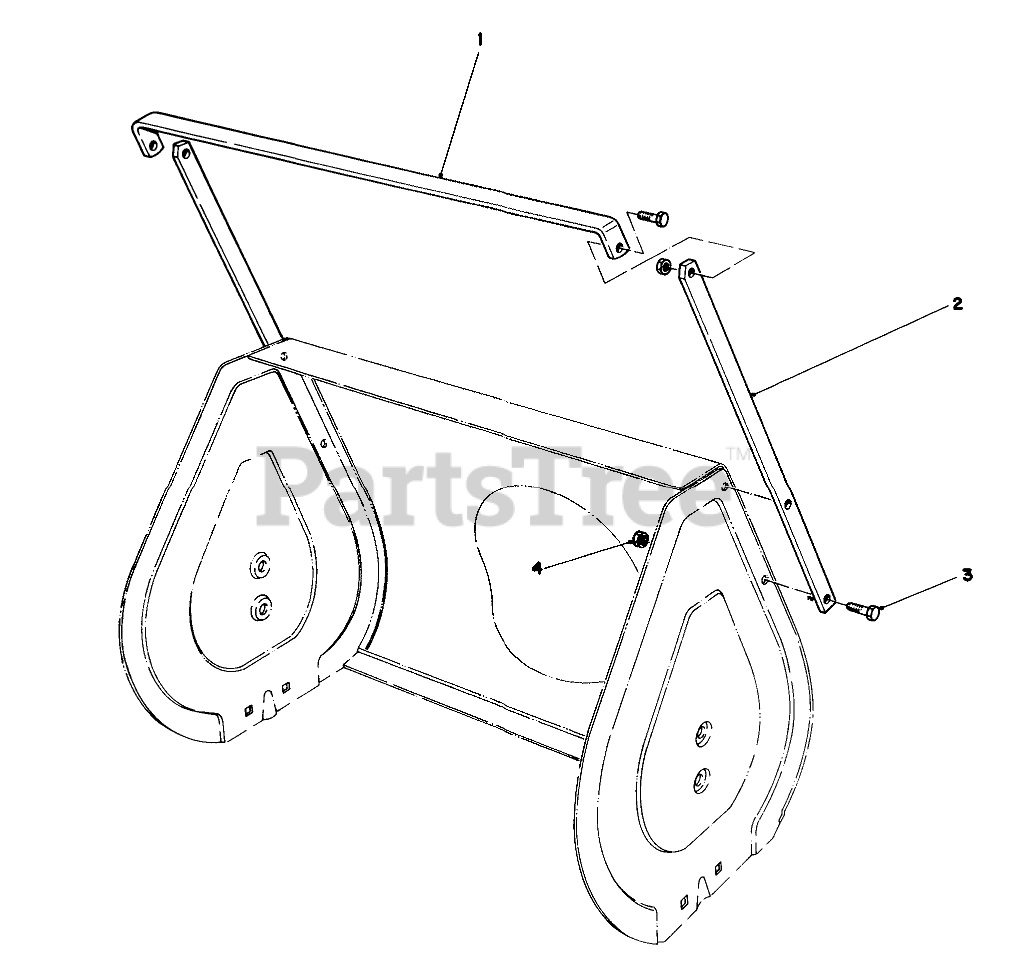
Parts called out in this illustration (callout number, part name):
1	Drift Breaker-Top
2	Drift Breaker-Side
3	SCREW-HH
4	NUT-LOCK, NI
